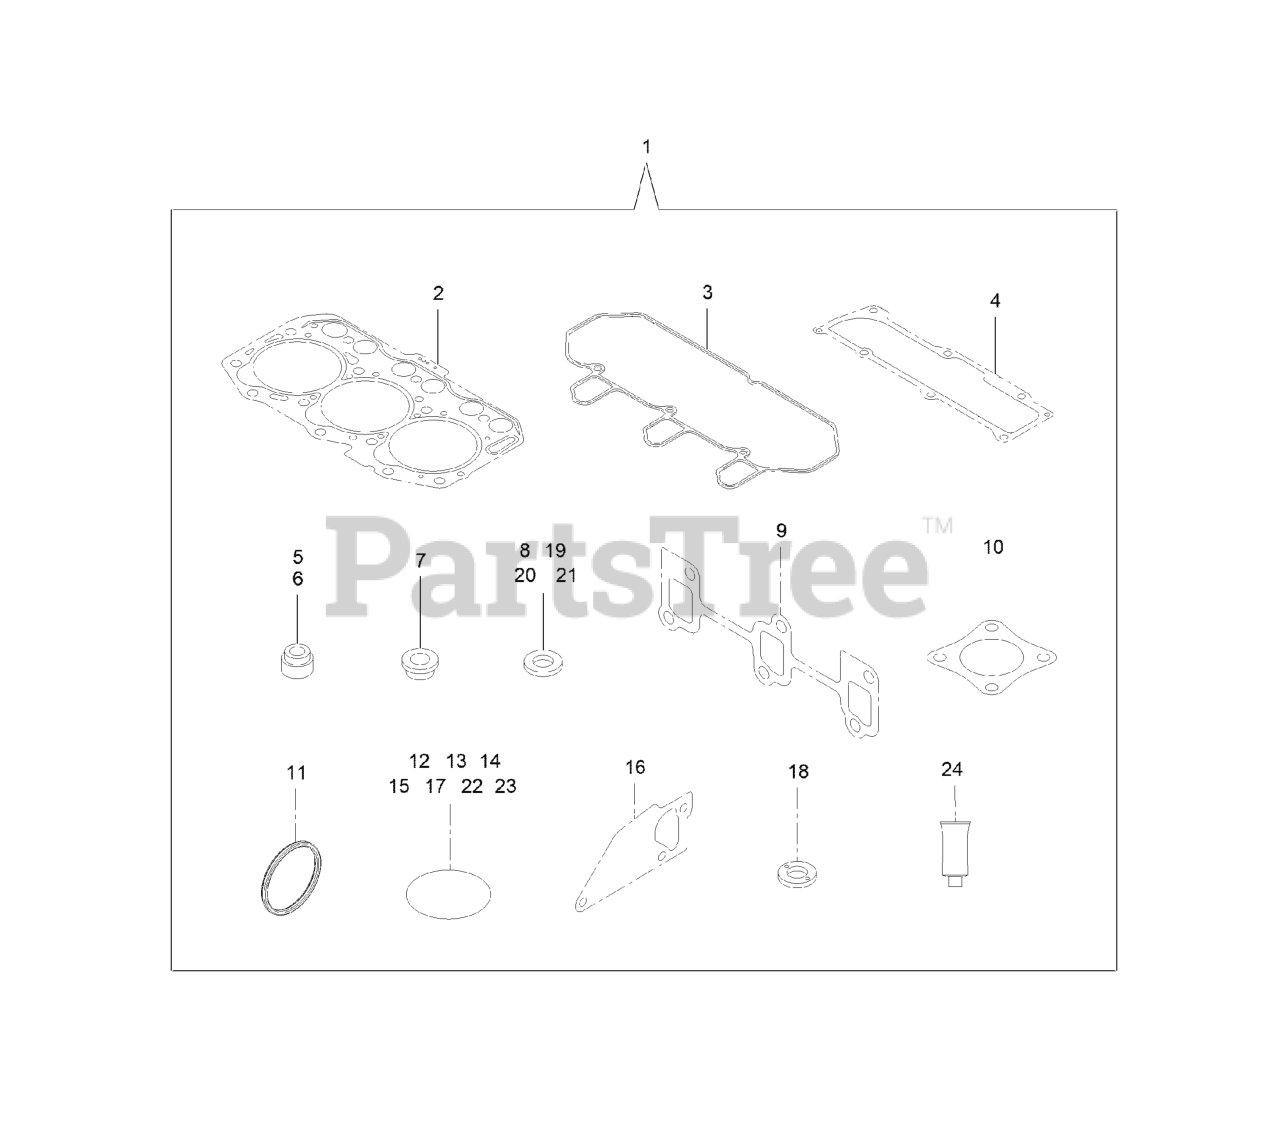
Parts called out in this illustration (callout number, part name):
1	GASKET KIT
2	GASKET SET-HEAD
3	GASKET-BONNET
5	SEAL-STEM, VALVE
6	SEAL-STEM, VALVE
7	PROTECTOR-NOZZLE
8	GASKET-NOZZLE
9	GASKET-EXH MANIFOLD
10	GASKET-SILENCER
11	GASKET-WASHER
16	GASKET-WATER PUMP
19	WASHER-SEAL
20	WASHER-SEAL
24	Gasket-Liquid
